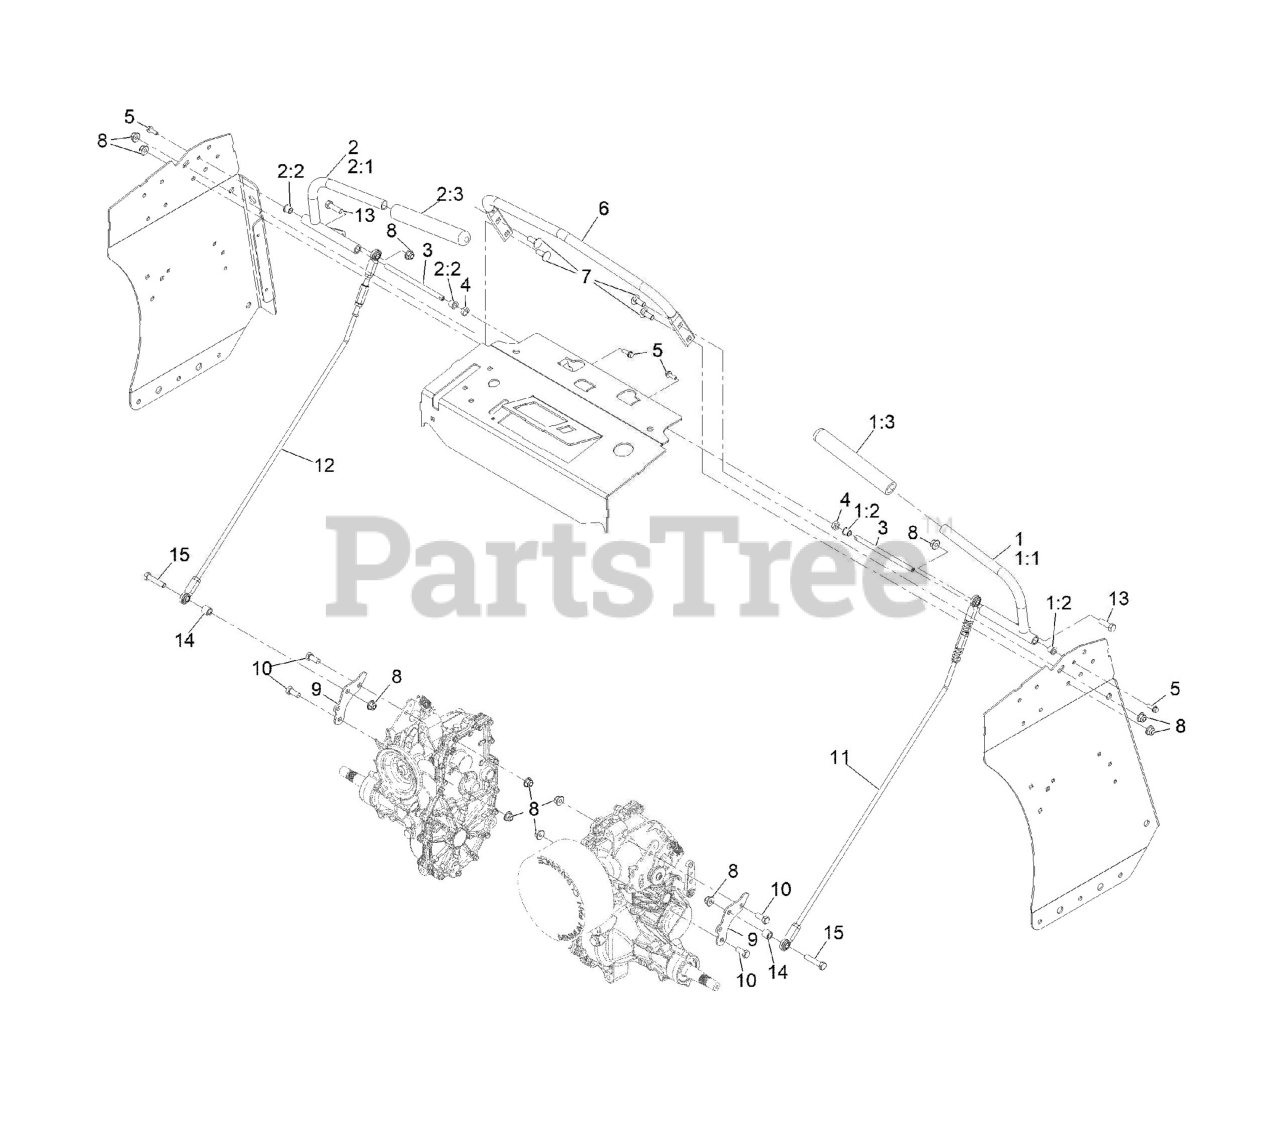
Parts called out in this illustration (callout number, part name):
1	LH Motion Handle ASM
1:1	HANDLE-CONTROL, LH
1:2	BEARING
1:3	GRIP-LEVER, CONTROL
2	RH Motion Handle ASM
2:1	HANDLE-CONTROL, RH
2:2	BEARING
2:3	GRIP-LEVER, CONTROL
3	SHAFT-PIVOT, MOTION CONTROL
4	SPACER-SHAFT, DRIVE LEVER
5	SCREW-HHF
6	BAR-REFERENCE
7	BOLT-CARR
8	NUT-HF, NI
9	ARM-MOTION
10	SCREW-HH
11	LH Motion Linkage ASM
12	RH Motion Linkage ASM
13	SCREW-HH
15	SCREW-HH
